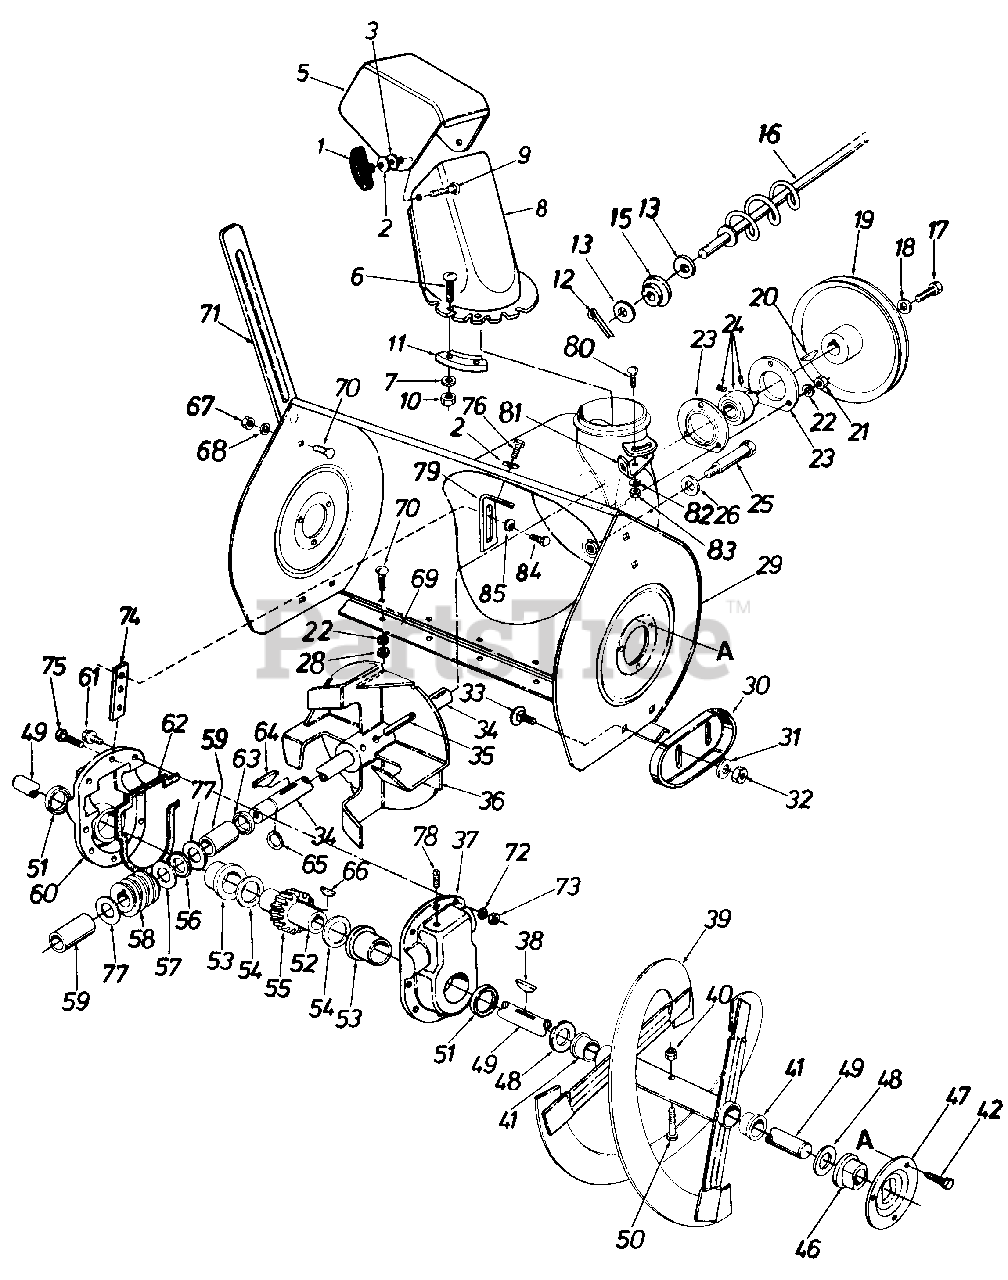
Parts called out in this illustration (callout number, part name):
1	Hand Knob Ass'y.
2	Bell-Wash. .345 I.D. x .88 O.D. x .060
3	Fl. Wash. .312 I.D. x 1.125 O.D. x .125
5	Top Chute
6	Truss Mach. Scr. 1/4-20 x .75"
7	Fl-Wash. 1/4" I.D.
8	Chute
9	Carr. Bolt 5/16-18 x 1.00" Lg.
10	Hex Cent. L-Nut 1/2-20 Thd.
11	1 Chute Flange Keeper
12	Cotter Pin
13	Fl-Wash. .385" I.D. x .62"
15	Bushing
16	Chute Crank Ass'y.
17	Hex L-Scr. 5/16-18 x .88" Lg.
18	Bell-Wash. .345 I.D. x .88
19	V-Pulley .875 I.D. x 10.12
20	#9 Hi-Pro Key 3/16 x 3/4" Dia.
21	Hex Nut 5/16-18 Thd.
22	L-Wash. 5/16" I.D.
23	Bearing Hsg. Self Aligning Brg.
24	Self Aligning Brg. .875 I.D.
25	Stud 3/8-16 x 2.75" Lg.
26	Bell-Wash. .400 I.D. x .88 O.D. x .060
28	Hex Nut 5/16-18 Thd.
29	Blower Hsg. Ass'y.
30	Slide Shoe
31	Bell-Wash. .400 I.D. x .88 O.D. x .060
32	Hex Jam Nut 3/8-16 Thd.
33	Carr. Bolt 3/8-16 x .62" Lg.
34	Blower Axle
35	Spring Pin Spiral 5/16" Dia. x 1.75" Lg.
38	#91 Woodruff Key 1/4" x 3/4" Dia.
39	Spiral Ass'y. L.H.
40	Hex Ins. L-Nut 5/16-18 Thd.
41	Plastic Bushing
42	Hex Wash. Hd. Tap Scr. 5/16-24 x .62" Lg.
46	Flange Brg. w/Flats 1.0" I.D.
47	Bearing Hsg. Spiral Hsg.
48	Fl-Wash. 1.06 I.D. x 1.75" O.D. x .100
49	Spiral Axle
50	Hex Bolt 5/16-18 x 1.75" Lg.
51	Oil Seal 1.50" I.D.
52	Worm Gear Shaft
53	Flange Brg. 1.503 I.D.
54	Fl-Wash. 1.5 I.D. x 2.0 O.D.
55	Double Threaded Worm Gear
56	Thrust Brg. .88 I.D. x 1.44 O.D. x .078
57	Fl-Wash. .88 I.D. x 1.40 O.D.
58	Double Threaded Worm L.H.
59	Sleeve Brg. .875 I.D.
60	Complete Gear Hsg. Half R.H.
61	Hex Bolt 5/16-18 x 1.0" Lg.
62	Gasket
63	Oil Seal .875" I.D.
64	#9 Hi-Pro Key 3/16 x 3/4" Dia.
65	Snap Ring .875" Dia.
66	#91 Woodruff Key 1/4 x 3/4" Dia.
67	Hex Nut 5/16-18 Thd.
68	L-Wash. 5/16" I.D.
70	Carr. Bolt 5/16-18 x .62" Lg.
72	Wave Wash. 5/16" I.D.
73	Hex Ins. L-Nut 5/16-18 Thd.
74	Gear Hsg. Support Plate
75	Hex Bolt 5/16-18 x 1.25"
76	Hex Wash. Hd. Self-Tap Scr. 5/16-18 x .75" Lg.
77	Fl-Wash. .88 I.D. x 1.40 O.D.
78	Filler Plug
80	Carr. Bolt 5/16-18 x .75" Lg.
82	Bell-Wash. .345 I.D. x .88"
83	Hex Nut 5/16-18 Thd.
84	Hex Bolt l/4-28 x .75" Lg.
85	Bell-Wash. .28" I.D. x .75" O.D.
